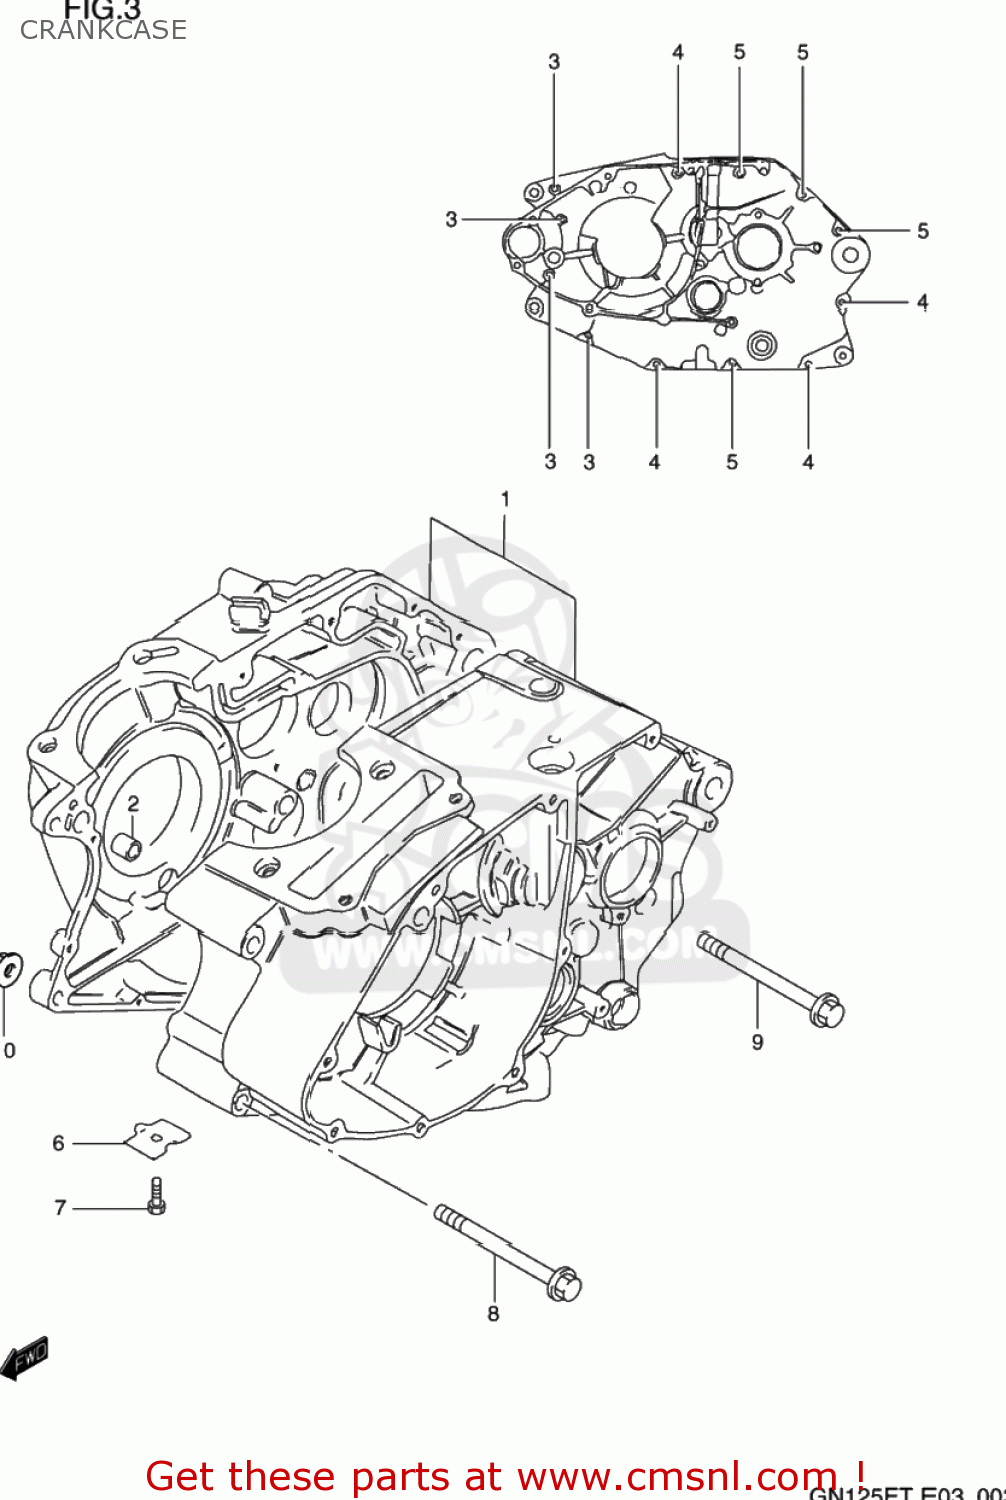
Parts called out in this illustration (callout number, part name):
1	CRANKCASE SET
2	PIN
3	BOLT
4	BOLT
5	BOLT
6	PLATE,OIL GALLERY PLUG
7	BOLT
8	BOLT(8X80)
9	BOLT(8X88)
10	NUT
